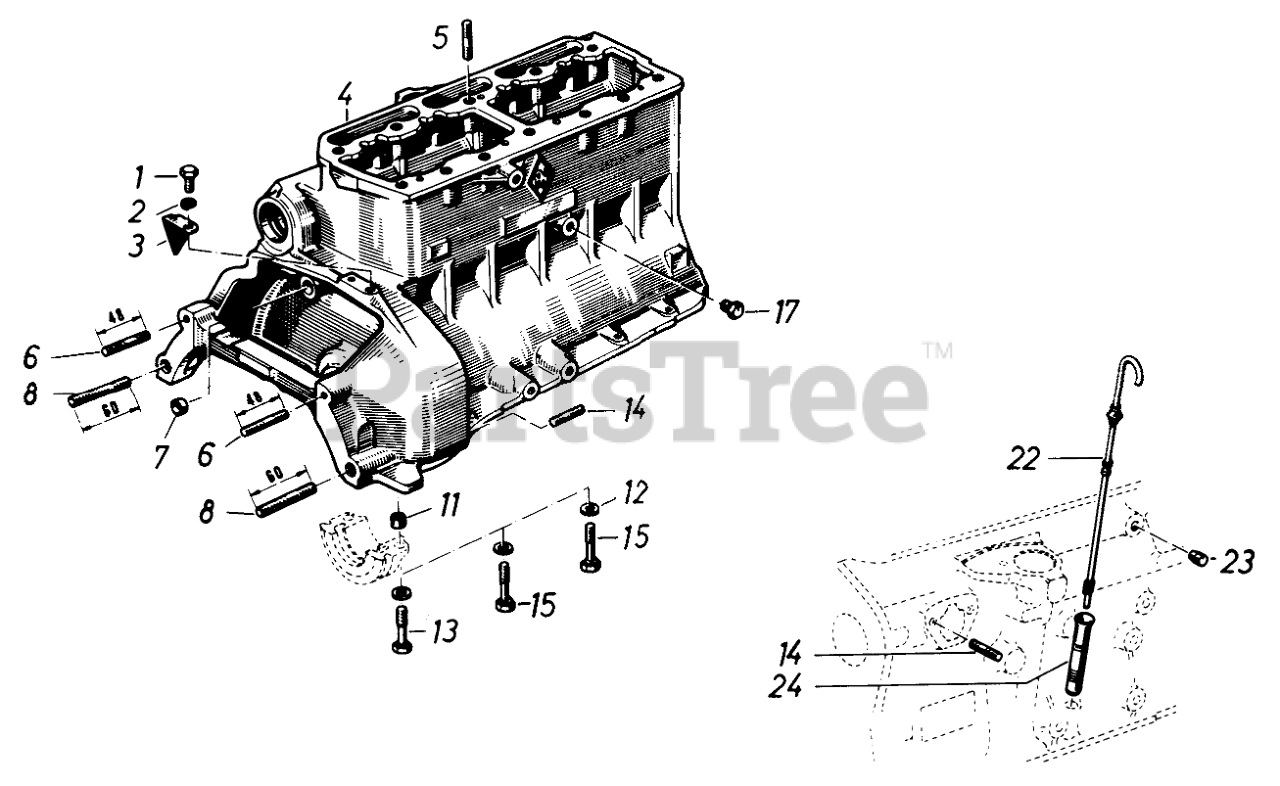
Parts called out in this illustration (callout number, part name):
1	Screw
2	Lockwasher
3	Indicator
4	Cylinder Housing
11	Bushing
12	Washer
13	Screw
15	Screw
22	OIL LEVEL DIPSTICK
24	Tube for Oil Level Dipstick
